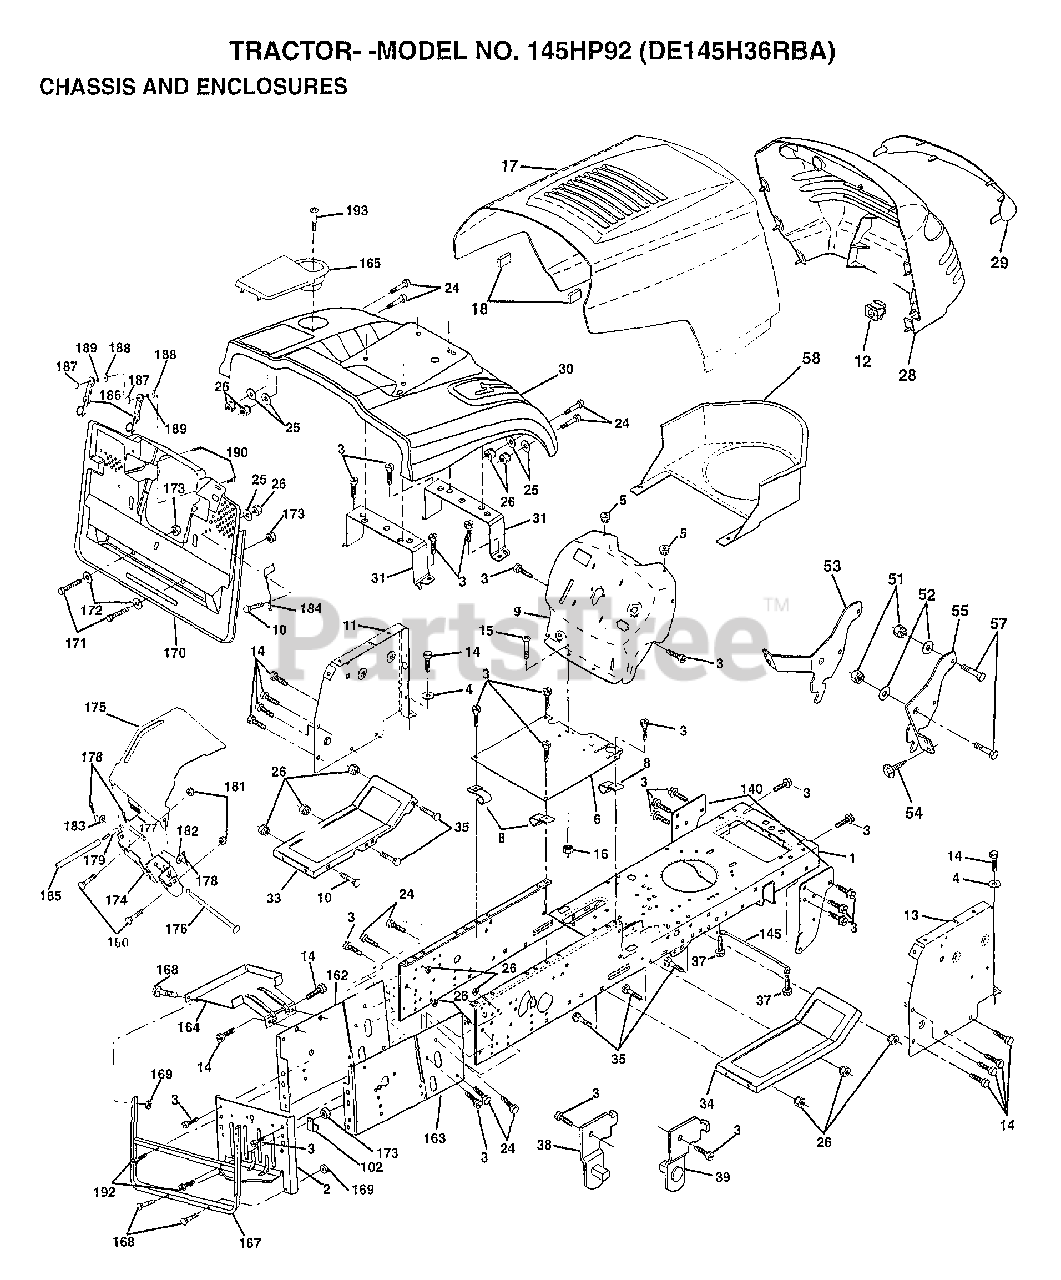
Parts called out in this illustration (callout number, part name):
1	CHASSIS.STAMPING
2	DRAWBAR.CRD
3	SCREW
4	WASHER
5	BUMPER-HOOD/DASH
6	SADDLE
8	"CLIP,INSULATOR"
9	DASH.SILKSCREEN
11	"PANEL-DASH,LH"
12	CLIP.TINNERMAN
14	SCREW LT
15	SCREW
20	"PLATE-MTG,BATT/FU"
24	BOLT
25	WASHER
26	NUT
28	GRILL
30	FENDER.CRD.SAGE
31	BRKT.SUPT.FENDER.CRD
33	FOOTREST
34	FOOTREST.PNT.RH
35	BOLT
37	SCREW LT
38	BRACKET ASM LH
39	BRACKET ASM RH
51	NUT
52	WASHER
53	BRACKET.GRILLE.LH
54	SCREW.HEX.WS.HD
55	BRACKET.GRILLE.RH
58	AIR DUCT
102	CLIP T
125	SCREW
140	BRKT SUSPENSION
145	"ROD POVOT,CHASSIS"
148	SCREW
162	BRKT.EXT.CHASSIS.LH.CRD
163	BRKT.EXT.CHASSIS.RH.CRD
164	SUPPORT.BATTERY.CRD
165	COVER.BATTERY.CRD.BLACK.LT
167	SUPT.ASM.BACKPLATE
168	BOLT-RD HD SQ NK
170	COVER.BACKPLATE.BLACK
171	BOLT.HEX.3/8-16X2-1/2
173	NUT
174	BRKT.SWITCH.FBI.CRD
175	GRUARD.DOOR.REAR.CRD
176	HINGE PIN
177	SPRING.COVER.LH
179	ROD.PIVOT.FBI.CRD
182	WASHER.385X.625
183	WASHER
184	BRKT.ACTUATOR.BAG.CRD
185	TUBE.LEVER.SWCH.FBI.CRD
186	LATCH ASSY.BAGGER
187	WELDNUT
188	WASHER #10
189	LOCKWASHER
190	SCREW
192	SCREW LT
193	SCREW LT
